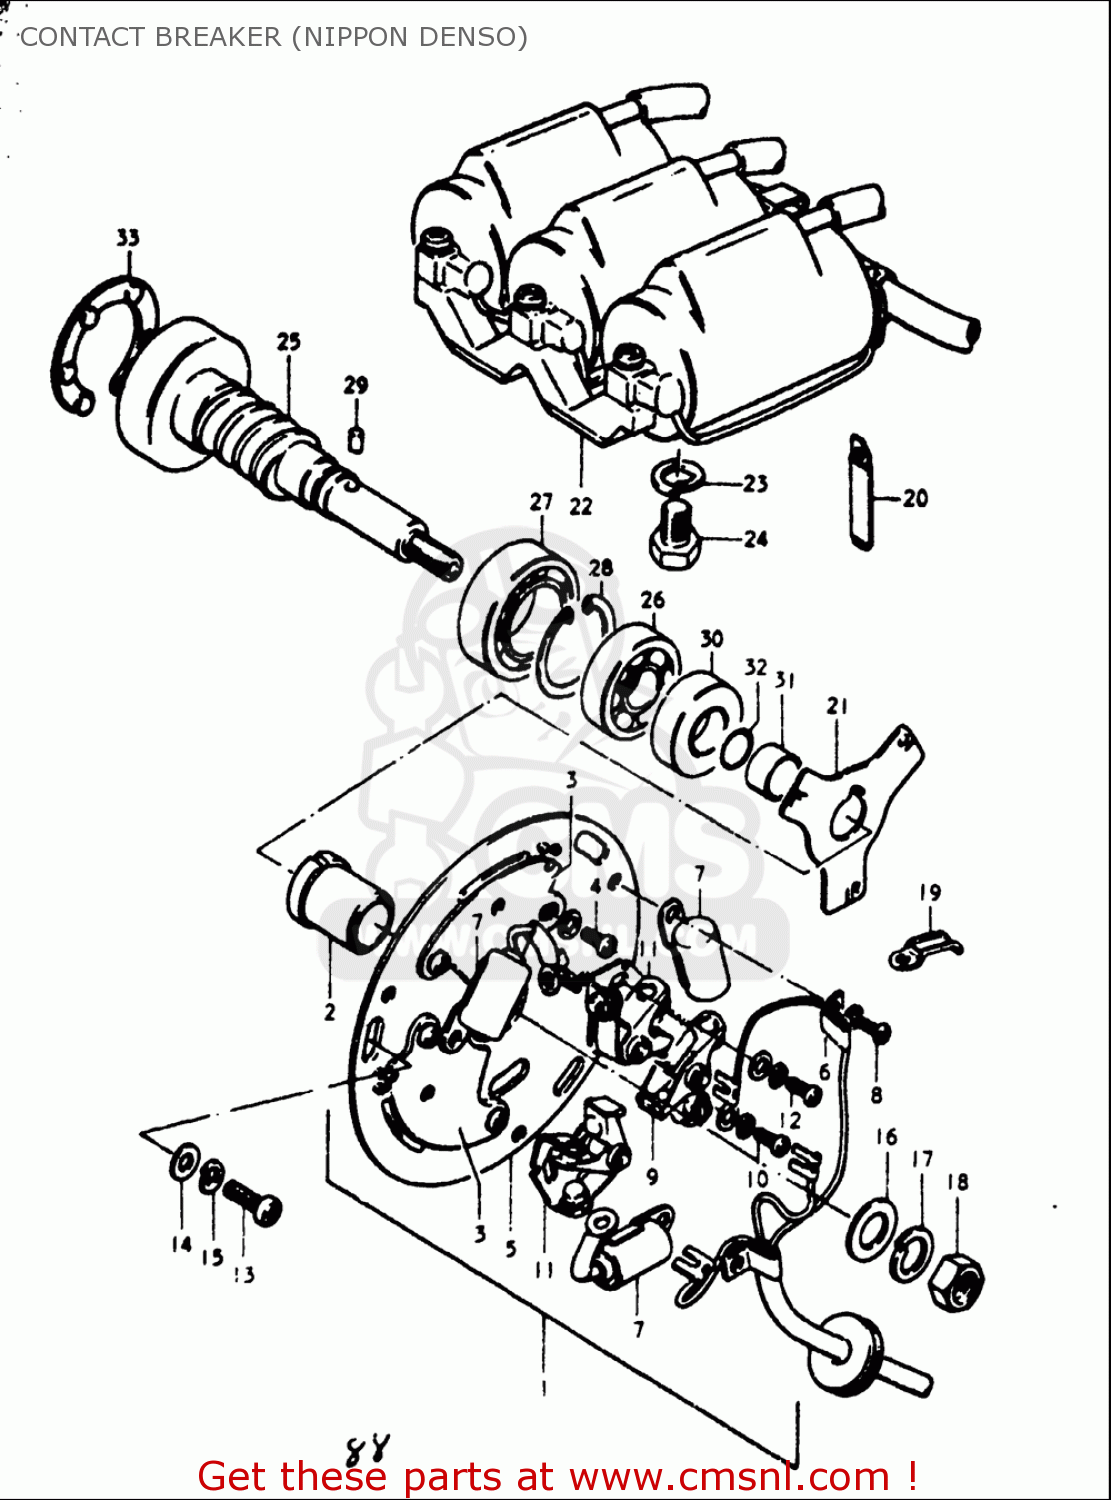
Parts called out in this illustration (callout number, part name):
4	SCREW 4X6
7	CONDENSER
8	SCREW
9	POINT ASSY
10	SCREW 4X6
11	POINT ASSY
12	SCREW 4X6
13	SCREW(5X12)
14	WASHER
15	WASHER,LOCK
16	WASHER
17	WASHER,LOCK
18	NUT
19	CLAMP
23	WASHER,LOCK
24	BOLT
26	BEARING
27	BEARING(25X47X8)
28	CIRCLIP
29	PIN
30	SEAL,OIL(20X35X7)
32	O RING(D:2.4,ID:11.8)
